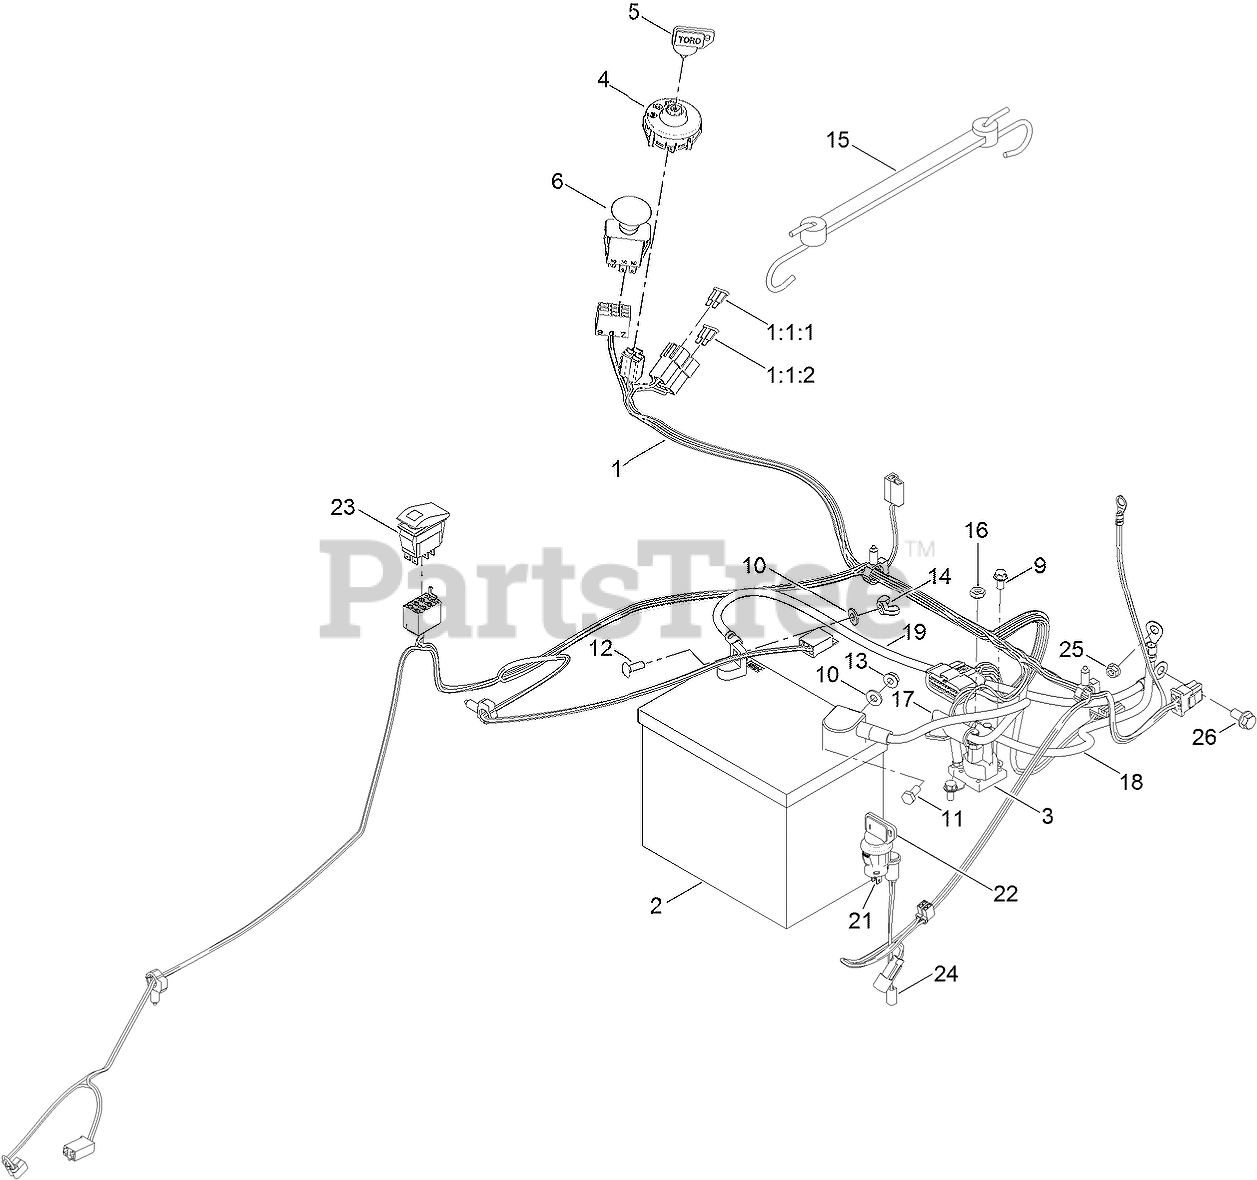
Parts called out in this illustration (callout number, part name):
1	HARNESS-WIRE
1:1	HARNESS-WIRE
1:1:1	FUSE-BLADE, 30 AMP
1:1:2	FUSE-BLADE, 25 AMP
2	BATTERY
3	SOLENOID
4	SWITCH-IGNITION
5	KEY-IGNITION
6	SWITCH-PTO, ON-ON
9	SCREW-HWH
10	WASHER-FLAT
11	SCREW-HH
12	BOLT-CARR
13	NUT-HF
14	NUT-WING
15	HOLDDOWN-BATTERY
16	NUT-JAM
17	CABLE-BATTERY, RED
18	CABLE-BATTERY, POSITIVE
19	CABLE-BATTERY, BLACK
21	SWITCH-MOMENTARY, N.O.
22	KEY-TORO
23	SWITCH-ROCKER, (ON)-OFF-(ON)
24	LIGHT-INDICATOR
25	NUT-HF
26	SCREW-HHF
